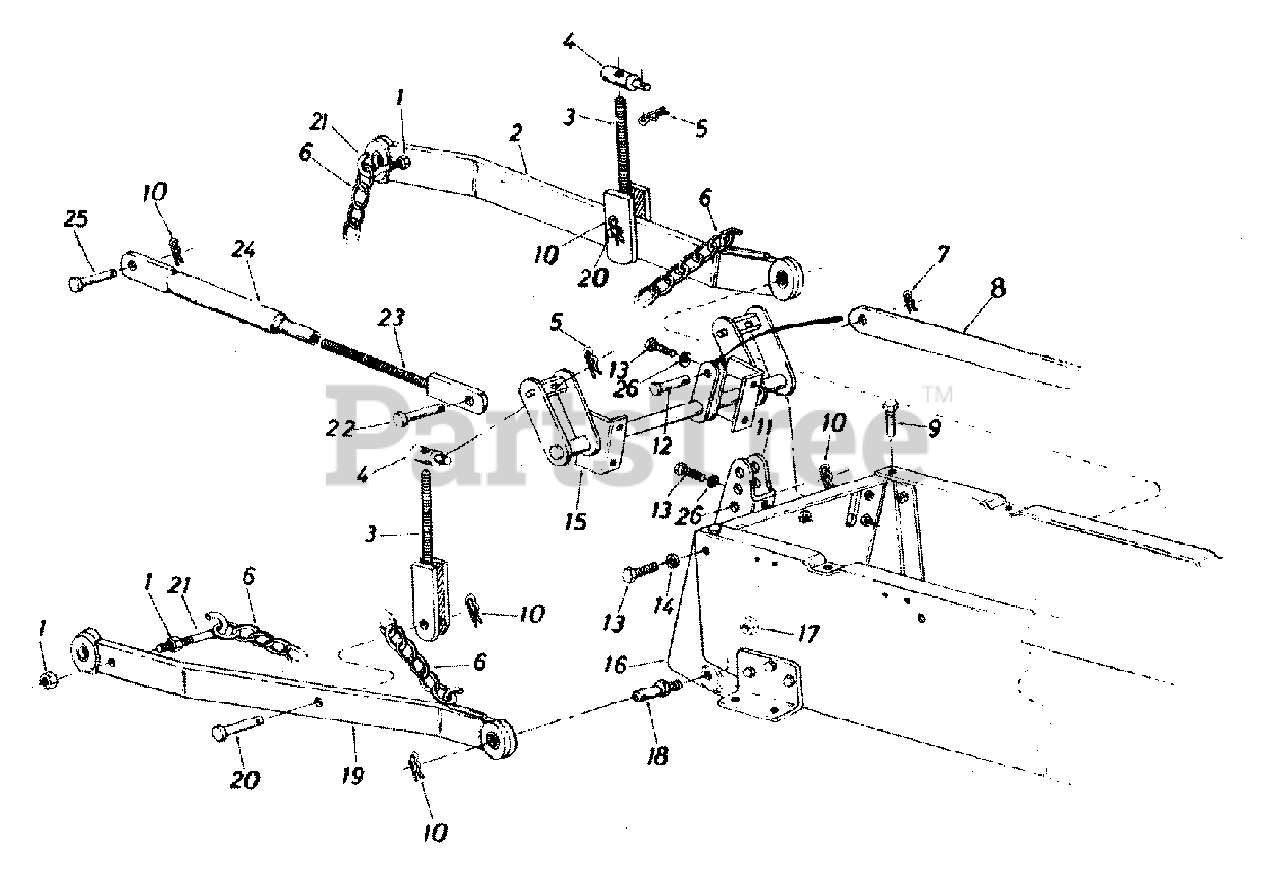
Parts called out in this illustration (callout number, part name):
1	Hex Cent. L-Nut 7/16-14 Thd.
4	Clevis Pin
5	Hitch Pin Clip
6	Chain - 20 Links
7	Cotter Pin 1/8" Dia. x 1.25" Lg.
8	Push Bar Ass'y.
9	Hex Scr. 3/8-16 x .75" Lg.
10	Hairpin Cotter
11	Hitch Brkt.
12	Clevis Pin
13	Hex Scr. 3/8-16 x .75" Lg.
14	L-Wash. 3/8" Scr. - H.D.
15	Rear Lift Shaft Ass'y.
16	Hitch Plate Ass'y.
17	Hex Cent. L-Nut 5/8-18 Thd.
18	Link Clevis Pin
19	Draft Bar Ass'y. - R.H.
20	Clevis Pin .63" Dia. x 1.66" Lg.
21	Hitch Chain Hook
22	Clevis Pin .63" Dia. x 2.4" Lg.
23	Clevis Screw
24	Clevis Tubing
25	Clevis Pin .63" Dia. x 2.4" Lg.
26	L-Wash. 3/8" Scr. - H.D.
